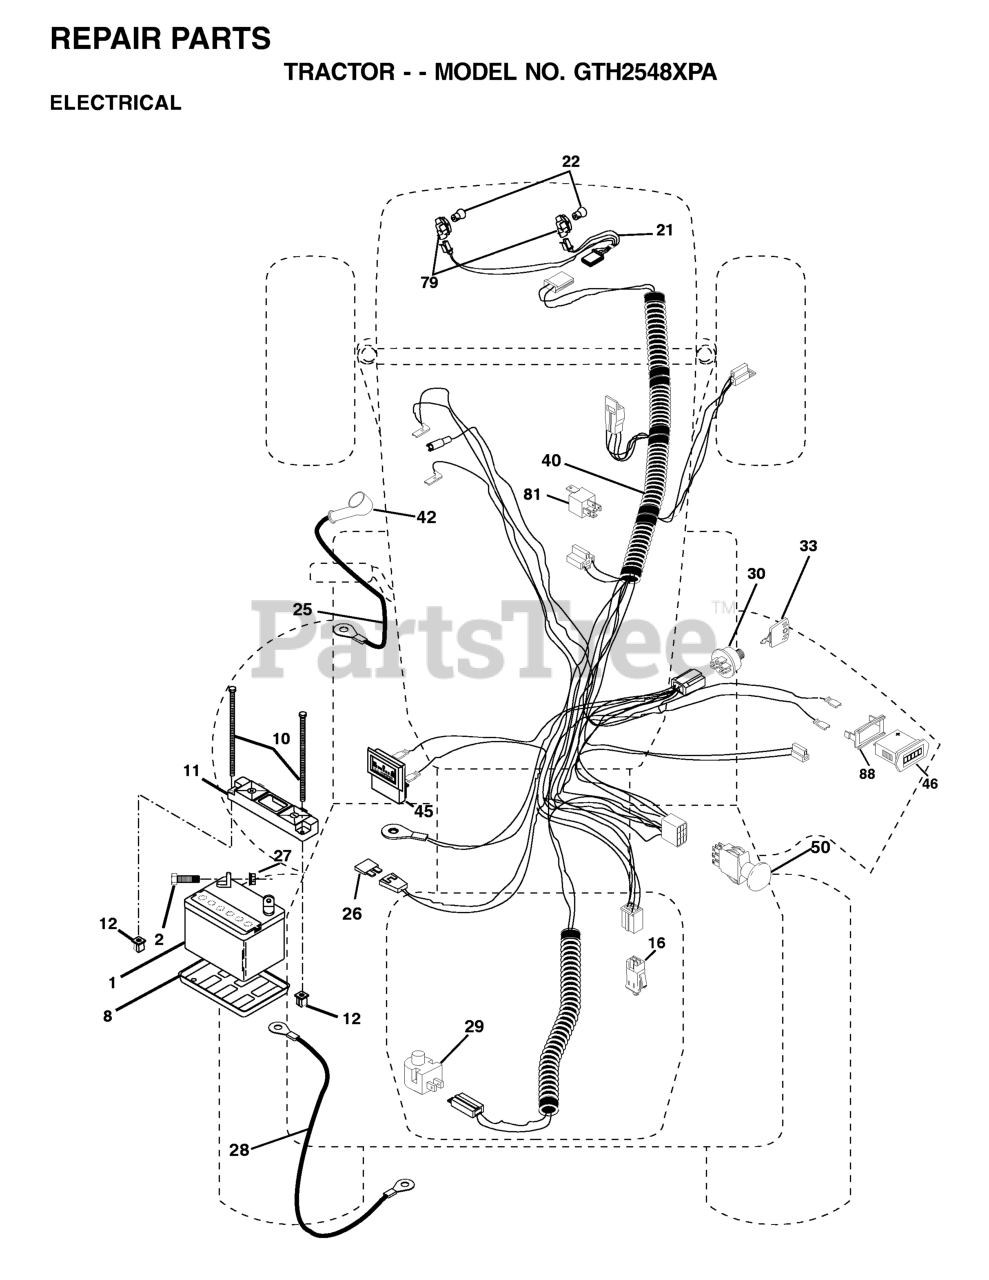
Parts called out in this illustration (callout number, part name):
1	BATTERY 12V .35 AMP
2	BOLT.HEX.1/4.X.3/4.DICHROMATE
8	BATTERY TRAY T
10	BOLT 1/4-20 X 7.5
11	BATTERY HOLDDOWN FRONT MOUNT
12	NUT, PUSH NYLON 1/4" BATTERY
16	SWITCH INTERLOOK PUSH-IN
21	HARNESS.W/LIGHT SOCKET
25	CABLE, BATTERY
27	NUT
28	CABLE, GROUND
29	PLUNGER SWITCH (COLOR:OLIVE)
30	IGNITION SWITCH
33	KEY MLD GEN DELTA
40	HARNESS, IGNITION
42	COVER.TERMINAL.RED
46	HOUR METER
50	RP.PTO.SWITCH.8 TERMINAL.BLACK
79	BULB HOLDER ASM.
81	RELAY.ASSY.T
89	BRACKET SNAP-IN HOURMETER
